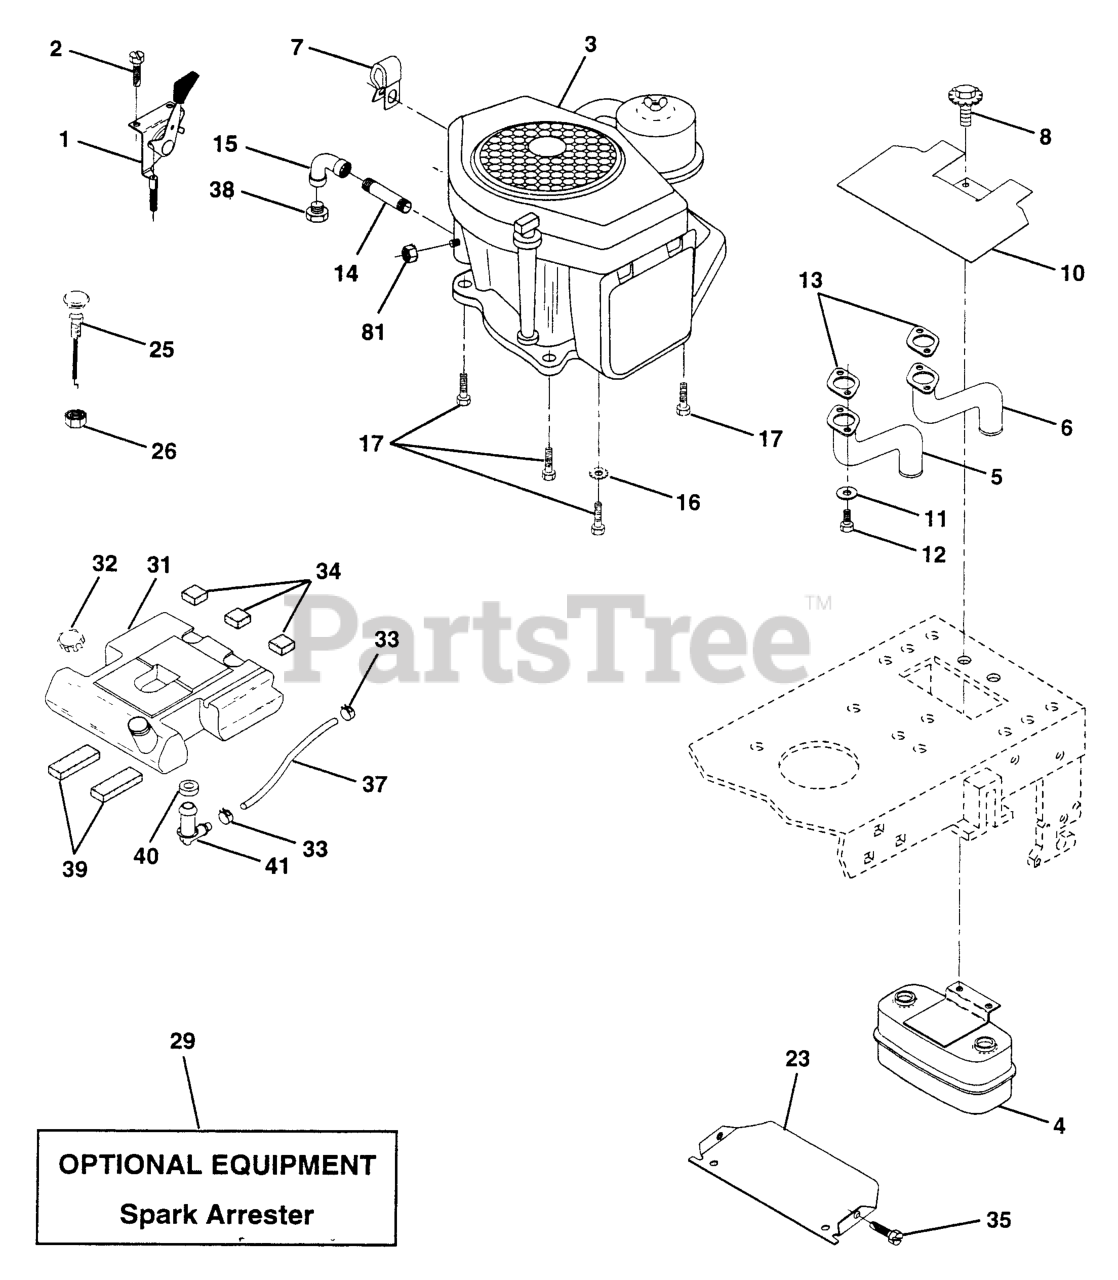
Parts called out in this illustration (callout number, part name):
1	CONTROL THROTTLE
2	SCREW LT
4	MUFFLER.TWIN.CYL.LOW.TONE
5	RP.PIPE-EXHAUST LH
6	RP.PIPE-EXHAUST RH
7	CLIP T
8	BOLT HEX WASHER HD 5/16-18
10	RP SHIELD HEAT MUFFLER
13	Muffler Gasket
14	Nipple Pipe 3/8 Npt X 4-1/2"
15	ELBOW
16	LOCKWASHER
17	SCREW LT
23	SHIELD HEAT
25	CONTROL, CHOKE
26	Nut, Keps 3/8-24 Unf
29	KIT.SPARK ARRESTOR 794945 B&S
31	FUEL TANK
32	FUEL CAP
33	HOSE CLAMP
34	PAD-SPACER LT
35	SCREW.THDROL.5/16-18X3/4.TTY
37	HOSE T
38	Plug Oil Drain
39	PAD IDLER TI
40	BUSHING OUTLET T
41	STEM FUEL TANK
81	NUT FLANGE 1/4-20 STARTER NUT
